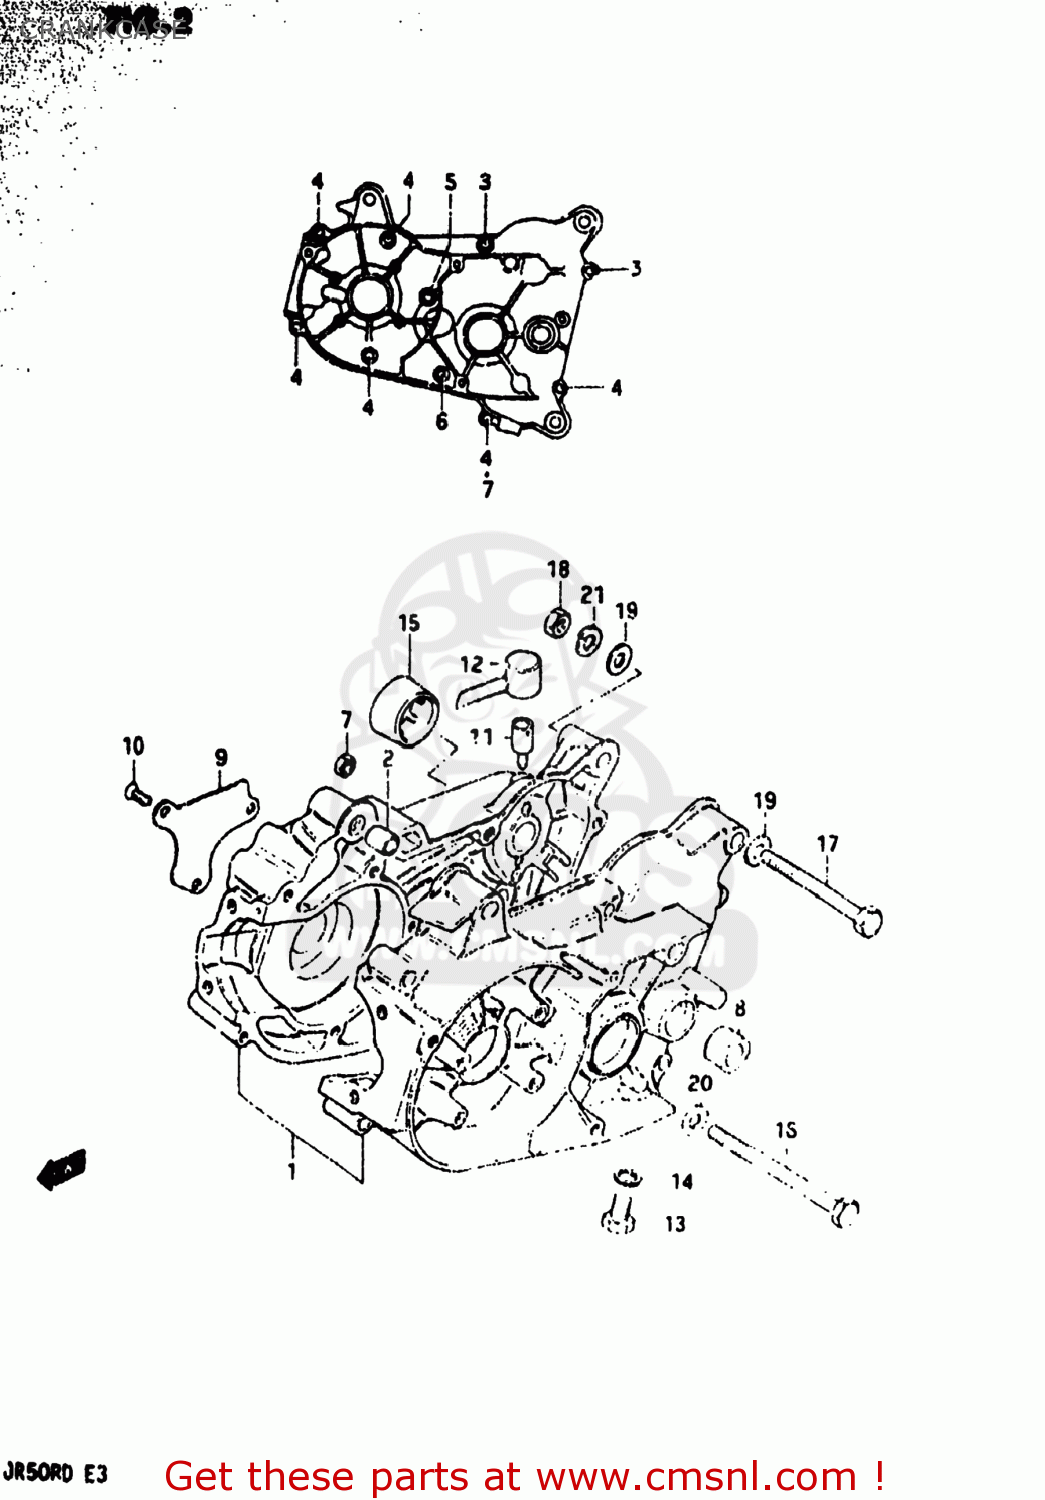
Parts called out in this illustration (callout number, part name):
1	CRANKCASE SET
2	PIN
3	SCREW 6X30
4	SCREW (6X35)
5	SCREW
6	SCREW
7	NUT
8	BUSH
9	PLATE,OIL RESERVOIR
10	SCREW
11	PLUG,TRANSMISSION BREATHER
12	GASKET (NAS)
13	PLUG
14	GASKET(10X14X3.6) (NAS)
15	SEPARATOR,BREATHER
16	BOLT
17	BOLT
18	NUT
19	WASHER
20	WASHER
21	LOCK WASHER
